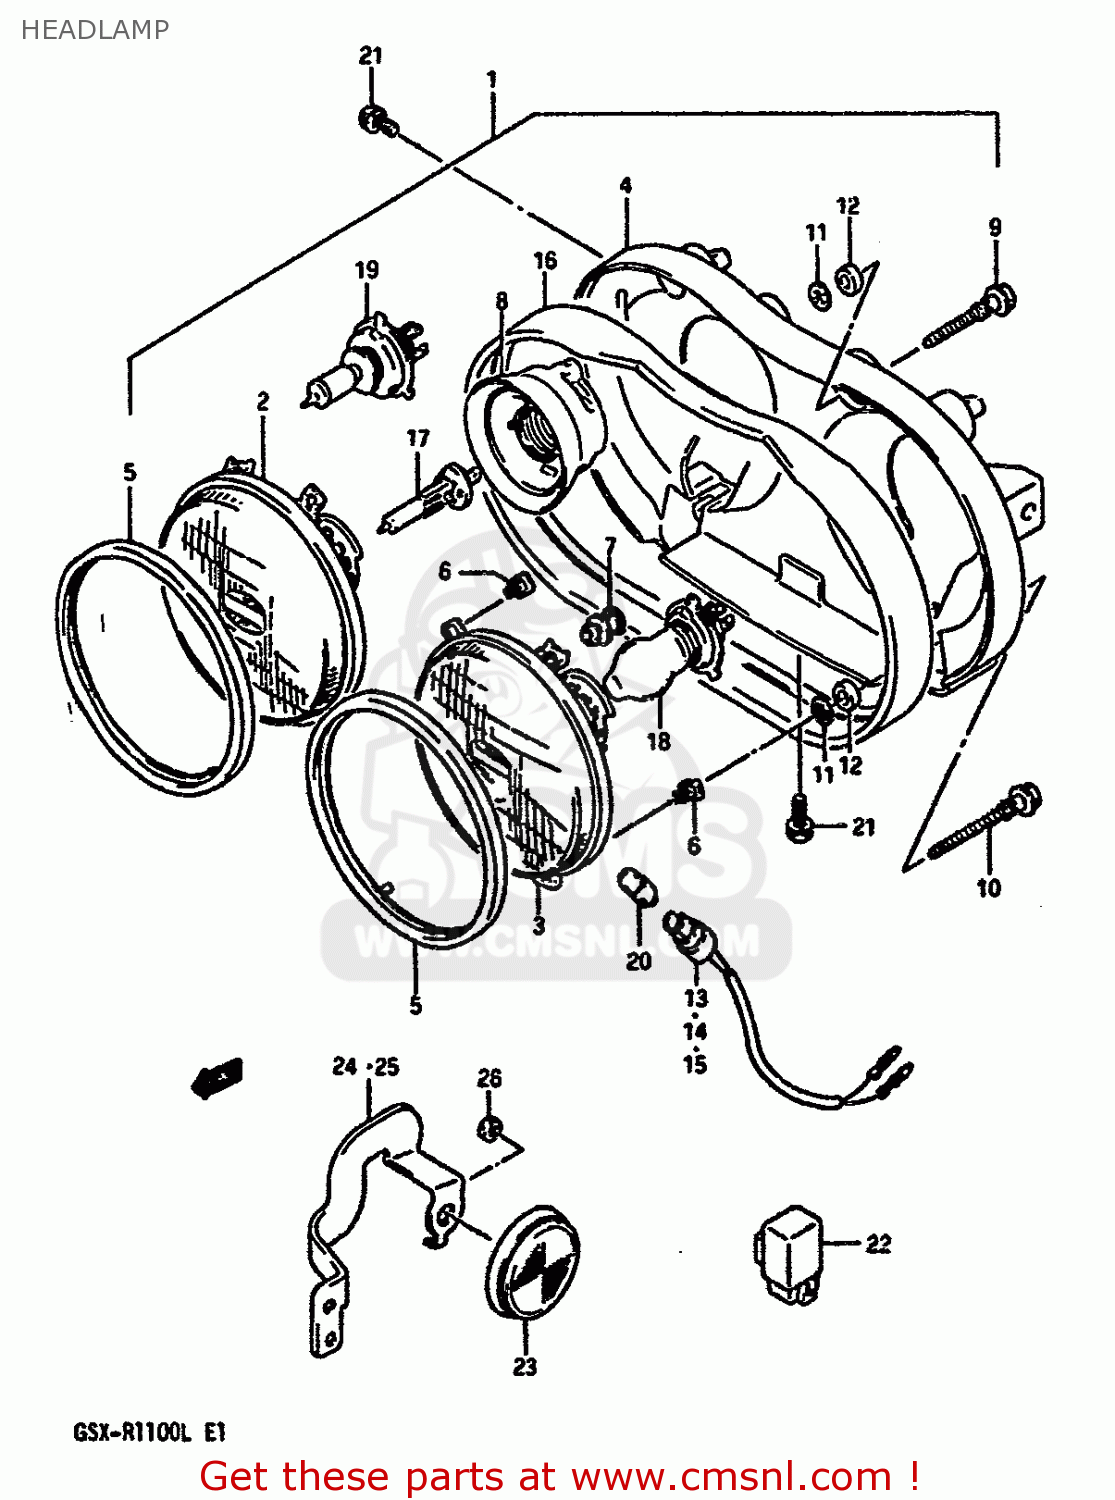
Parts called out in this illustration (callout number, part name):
1	HEADLAMP ASSY
2	UNIT,HEADLAMP RH
3	UNIT,HEADLAMP LH
4	HOUSING,HEAD LAMP
5	RING,RETAINING
6	NUT,HEADLAMP ADJUSTER
7	SCREW,SPHERICAL
8	COVER,SOCKET
9	SCREW,HEADLAMP ADJUST
10	SCREW,ADJUSTER
11	WASHER
12	BUSHING
13	SOCKET
14	SOCKET & CORD
15	SOCKET & CORD
16	GASKET,HEADLAMP HOUSING (NAS)
17	BULB(12V55W/H1/P14.5S/OSRA,PHI
18	BULB (12V, 60/55W, H4)
19	BULB(12V60/55W,H4)
20	BULB(12V4W)
21	SCREW
22	RELAY ASSY,HEADLAMP
23	REFLECTOR,REFLEX FR
24	BRACKET,FR SIDE RR,R
25	BRACKET,FR SIDE RR,L
26	NUT
